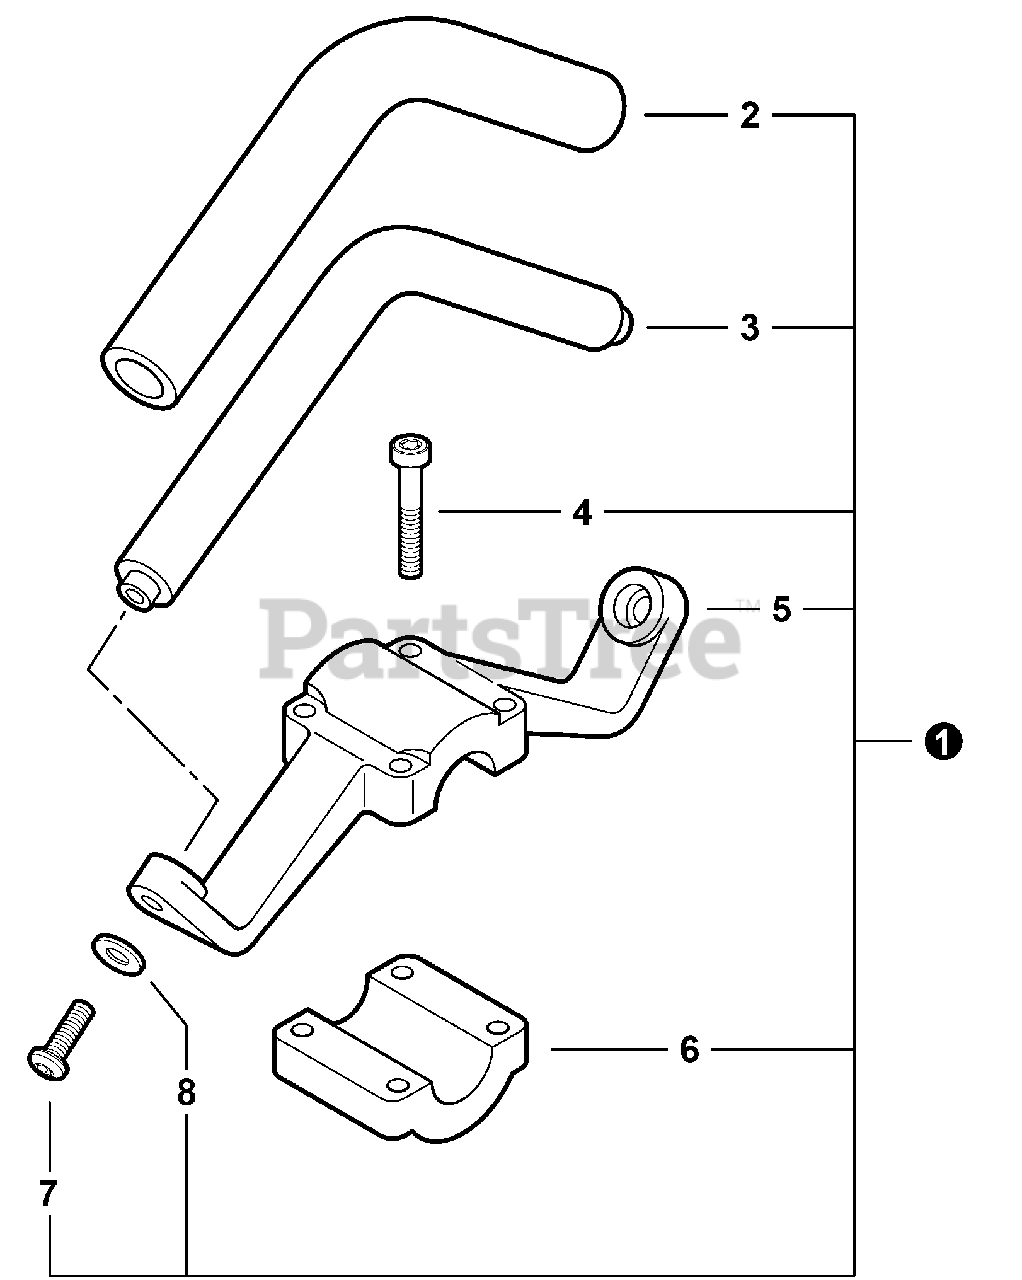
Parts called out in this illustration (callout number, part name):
1	FRONT HANDLE ASSY
2	GRIP, HANDLE
3	HANDLE - FRONT
4	SCREW - 5×30
5	BRACKET, HANDLE - UPPER
6	BRACKET, HANDLE - LOWER
7	SCREW - 5×20
8	WASHER - 5
